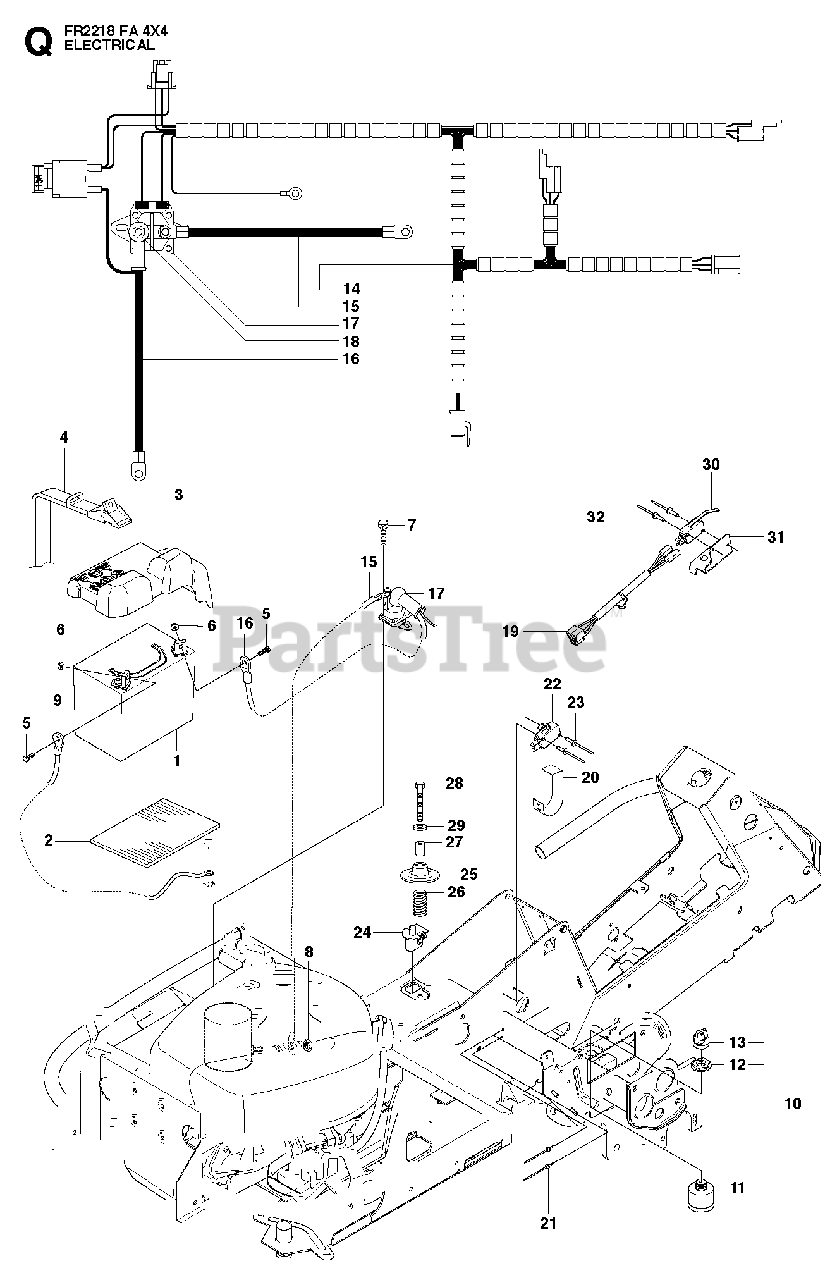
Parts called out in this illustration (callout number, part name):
5	SCREW EHHM
10	IGNITION SWITCH
11	IGNITION SWITCH
12	NUT
13	IGNITION KEY
19	WIRING
27	SPACER TUBE
28	SCREW
29	WASHER BRB 8.4X17
30	MICRO SWITCH
